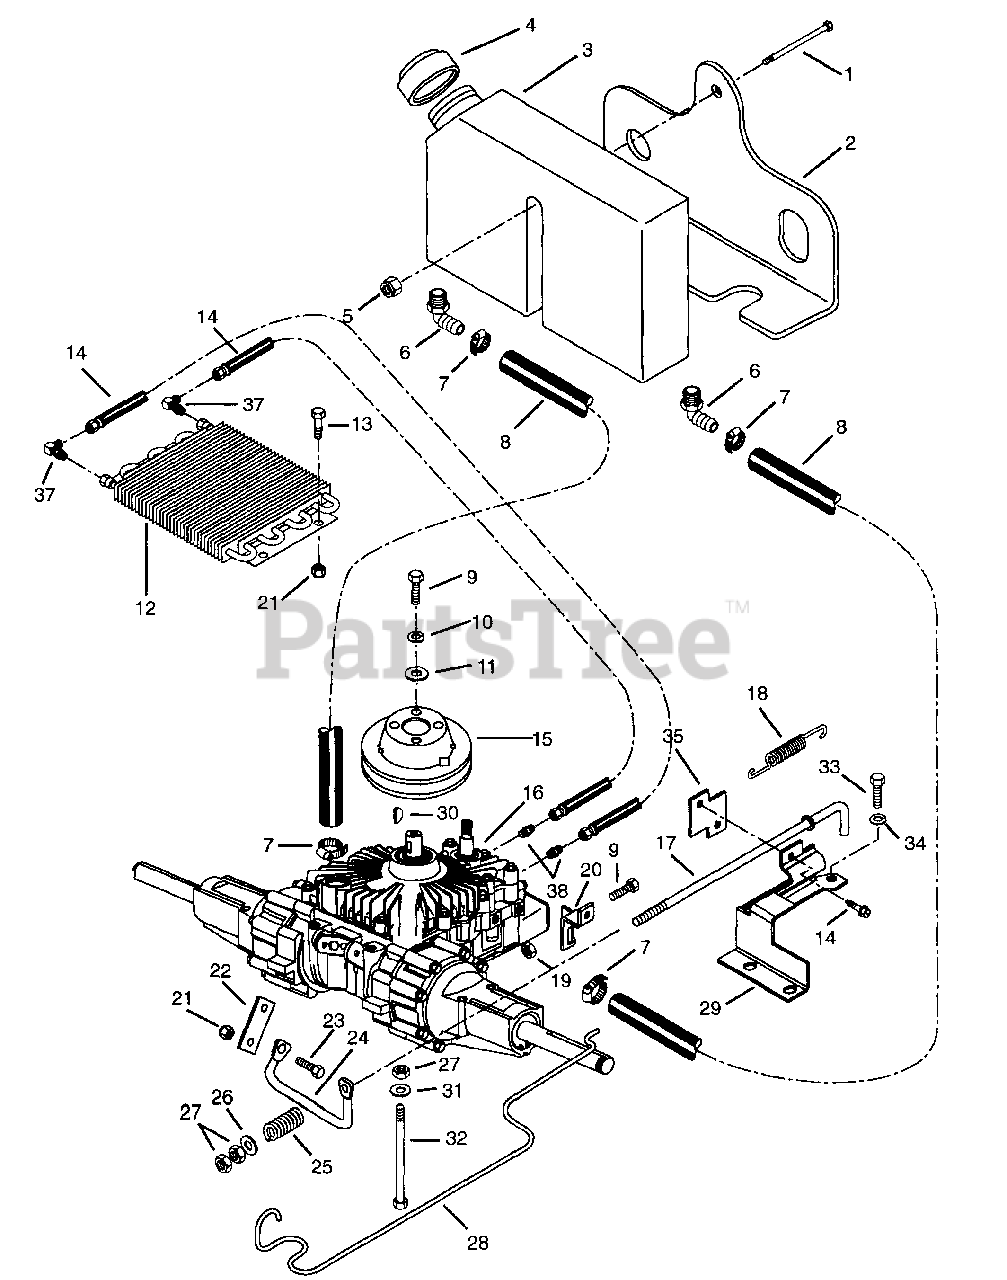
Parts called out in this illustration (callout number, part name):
1	Bolt-Hex .31-18 x 3.50
2	Tank Bracket
3	Tank, Hydraulic
5	Nut-Locking-Nylon .312-18
6	Elbow, Barbed .625
9	Bolt-Hex .25-20 x .75 Grade 5
10	Washer-Lock .250 x .077
11	Washer-Flat-Steel .328 x 1.0 x .094
12	Cooler, Oil
13	Bolt-Hex .25-20 x .63
14	Assembly, Hydraulic Hose
15	Transaxle Sheave
16	Transaxle
17	Rod, Parking Brake Pull
18	Spring-Tension .051 x .60 x 2.25
19	Nut .250-20
20	Arm, Dump Valve
21	Nut-Locking-Nylon .250-20
23	Bolt-Hex .25-20 x 1.00 Grade 5
24	Rod, Brake Pivot
25	Spring-Compression
26	Washer-Flat-Steel .406 x .812 x .065
27	Nut-Locking-Nylon .375-16 Grade 2
28	Rod, Dump Valve
29	Bracket, Brake Rod Pivot
30	Key Woodruff .19 x .63
31	Washer-Flat-Steel .406 x .812 x .065
32	Bolt-Hex .38-16 x 3.00
33	Bolt-Hex .31-18 x .50 Grade 5
34	Washer-Lock .313 x .078
35	Plate, Holding
36	Screw-Tapping .250-20 x .37
37	Adapter 3903-6-6
38	Adapter .56-18
